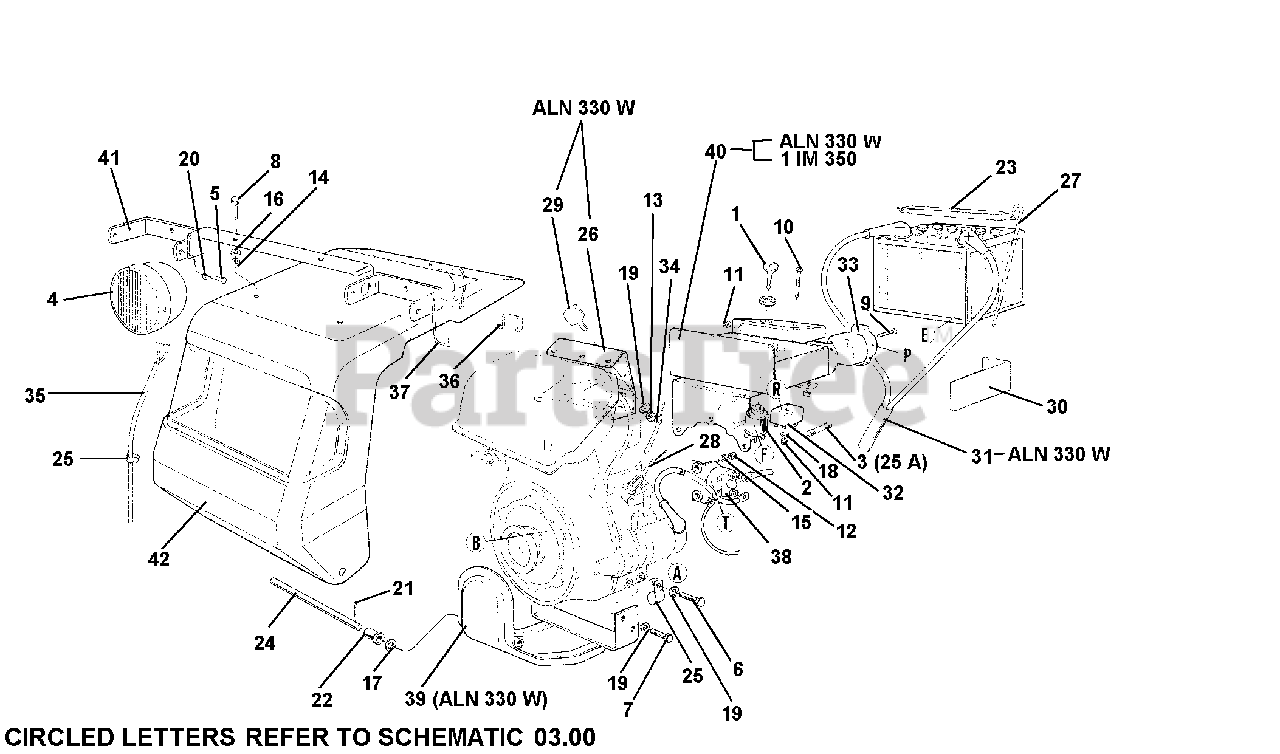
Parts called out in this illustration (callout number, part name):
3	FUSE 6 X 25 25A
5	SCREW TE M6 X 14
6	SCREW TE M8 X 12
7	SCREW M8 X 16
8	SCREW M8 X 25
9	SCREW TCCEI M4 X 30
10	SCREW TC M4 X 30 UNI 6107
14	NUT, SELF LOCKING M8
15	WASHER, FLAT 6.4
16	FLAT WASHER 9 X 24 UNI 6593
17	FLAT WASHER 10.5 X 21
18	LOCK WASHER B 4.3
19	WASHER, LOCK 8.4
20	WASHER, LOCK AZ 6.4 DIN 6798
21	PIN, COTTER A 3 X 20 UNI 1336
23	BATTERY BRACKET
24	PIN, COUPLING
25	CLAMP ENGINE
26	CONNECT. UPPER ELECTRIC ST.
27	BATTERY TIEROD
28	CABLE & SHEATH, ACCEL.LOMBAR
30	ANTISHOCK BAT
31	ELECTRIC START CABLES MC 715
33	7-POLE SOCKET
34	SHEATH CABLE
35	COVER CABLES
36	ELECTRIC STARTER HOOK
38	BOSCH RELAY 0332002160
39	HOOD LOWER COUPLING
40	SUPPORT BATTERY
41	LIGHT SUPPORT
